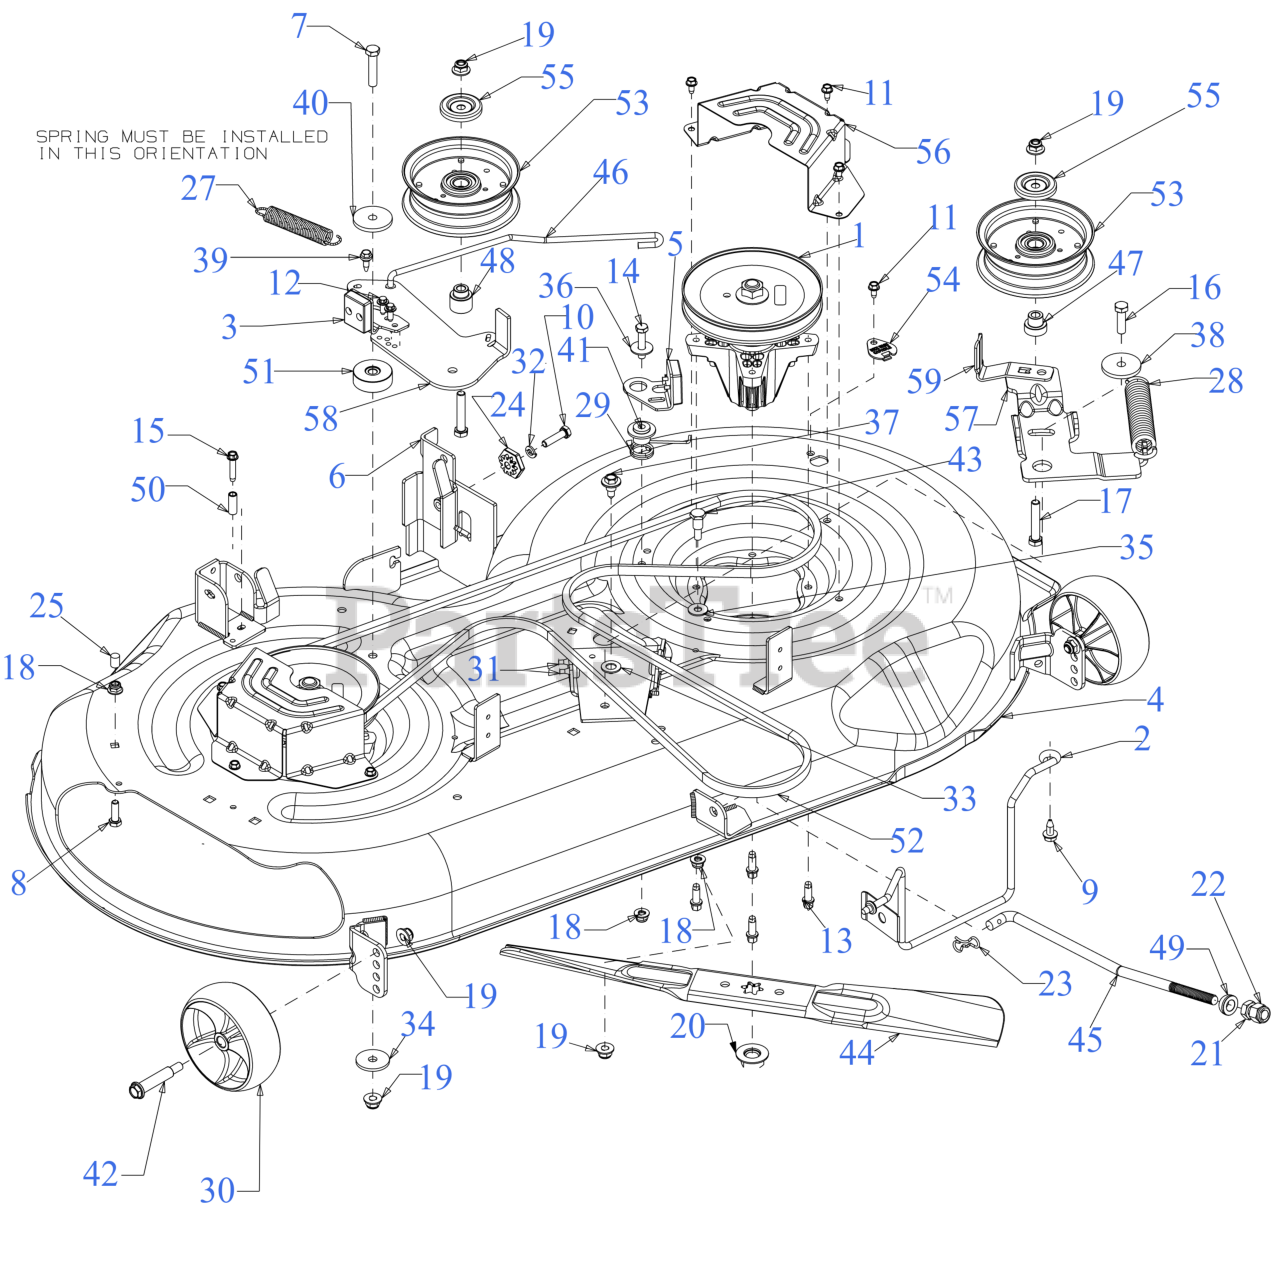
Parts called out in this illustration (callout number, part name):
1	SPINDLE ASSEMBLY-6.74" W/O ZERK
1	Troy-Bilt 46" SPINDLE ASSEMBLY (06989)
2	BELT KEEPER BRACKET ASSEMBLY (POWDER BLACK)
3	DECK BRAKE ASSEMBLY (RH)
4	46" DECK SHELL
5	DECK BRAKE ASSEMBLY
6	DECK HANGER BRACKET (LH)
7	HEX SCREW 3/8-16 x 1.75 GR5
8	SCREW 5/16-18 x 1.0 GR5
9	SCREW 5/16-18 x .750
10	SCREW 5/16-18 x 1.25 GR5
11	SCREW 1/4-20 X.500
12	SCREW M6-1 x .625
13	SCREW 5/16-18 x .875
14	SCREW 5/16-18 x 1.5 LG
15	SCREW 1/4-20 x 1.25
16	SCREW 3/8-16 x 1.25 GR5
17	SCREW 3/8-16 x 2.0 GR 8
18	FLANGE LOCK NUT 5/16-18
20	FLANGE NUT 5/8-18
21	HEX NUT
22	HEX LOCK NUT NYLON
23	PIN:COTTER
24	DECK ADJUSTMENT GEAR
25	VINYL CAP
27	EXTENSION SPRING
28	EXTENSION SPRING
29	TORSION SPRING
30	DECK WHEEL (5.0 DIA x 1.875)
31	BUMPER, .62 DIA x .3
32	LOCK WASHER 5/16
33	FLAT WASHER
34	FLAT WASHER .390x1.500x.134
35	FLAT WASHER
36	FLAT WASHER 344X1.00
37	SHOULDER SCREW .43X.29X5/16-18 TT
38	SHOULDER SPACER
39	SHOULDER SCREW
40	SHOULDER SPACER
41	DOUBLE SHOULDER SPACER .750 x .135
42	SHOULDER BOLT (.50 X 2.0 x 3/8 -16)
43	SHOULDER SCREW
44	23.25" BLADE (2N1) (STAR)
44	Genuine Factory Parts 46" BLADE SET(STAR 2IN1) (04290)
44	46" 6 PT STAR LOW LIFT/SAND BLADE
44	Cub Cadet 46" LOWLIFT BLADE SET
44	Genuine Factory Parts 46" LOWLIFT BLADE SET
44	23.25" BLADE (2N1) (XTREME) (STAR)
44	Cub Cadet BLADE SET (XTREME) 46" CUB 04290-X
45	DECK FRONT LIFT ROD
46	DECK BRAKE ROD
47	SHOULDER SPACER
48	SHOULDER SPACER
49	DECK LIFT PIVOT CUP
50	SPACER
51	SPACER .385ID x 1.75OD x .585THK
52	V-BELT A SEC x 103.24
52	Genuine Factory Parts 46" DECK DRIVE BELT
53	IDLER PULLEY 4.50" DIA
54	DECK WASH PLUG
55	IDLER PULLEY CAP
57	IDLER BRACKET 46T (LH)
58	DECK IDLER BRACKET
